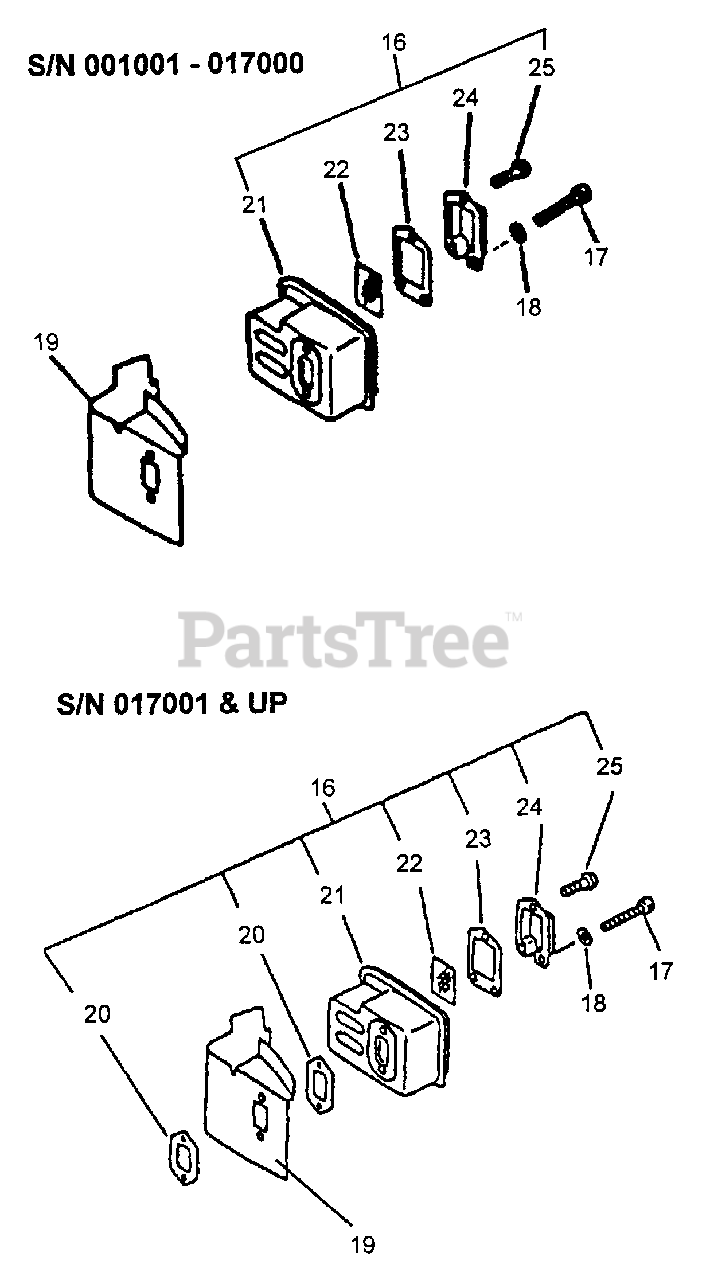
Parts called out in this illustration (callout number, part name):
16	MUFFLER ASSY
17	SCREW - 5X50
18	WASHER - 5
19	COVER, EXHAUST
19	SHIELD, EXHAUST
20	GASKET, EXHAUST
22	SCREEN, SPARK ARRESTOR
23	GASKET, EXHAUST
24	GUIDE, EXHAUST - OUTER
25	SCREW - 4X10
